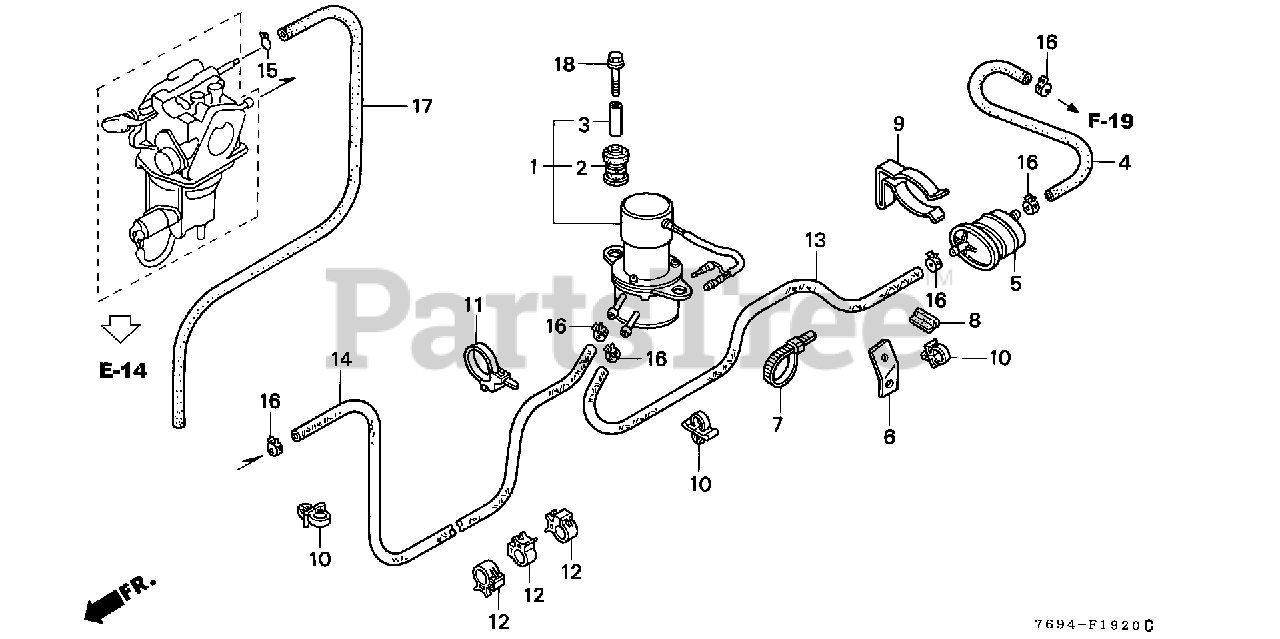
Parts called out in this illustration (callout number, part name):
1	PUMP ASSY., FUEL
2	RUBBER, FUEL PUMP SETTING
3	COLLAR, DISTANCE
4	TUBE, FUEL
5	FILTER, FUEL
6	PLATE, FUEL HOSE CLAMP
7	BAND B1, CABLE
8	SEAL A, COLUMN COVER (20MM)
9	CLAMP, FUEL STRAINER
10	CLIP, WIRE HARNESS
11	CLIP, HARNESS BAND (15)
12	CLIP, CABLE (15MM)
13	BULK HOSE, FUEL (5.5X8000) (5.5X430)
14	BULK HOSE, FUEL (5.5X8000) (5.5X860)
15	CLIP, TUBE (B7)
16	CLIP, TUBE (D10.5)
17	BULK HOSE, VACUUM (3.5X1000) (3.5X410)
18	BOLT, FLANGE (6X32)
